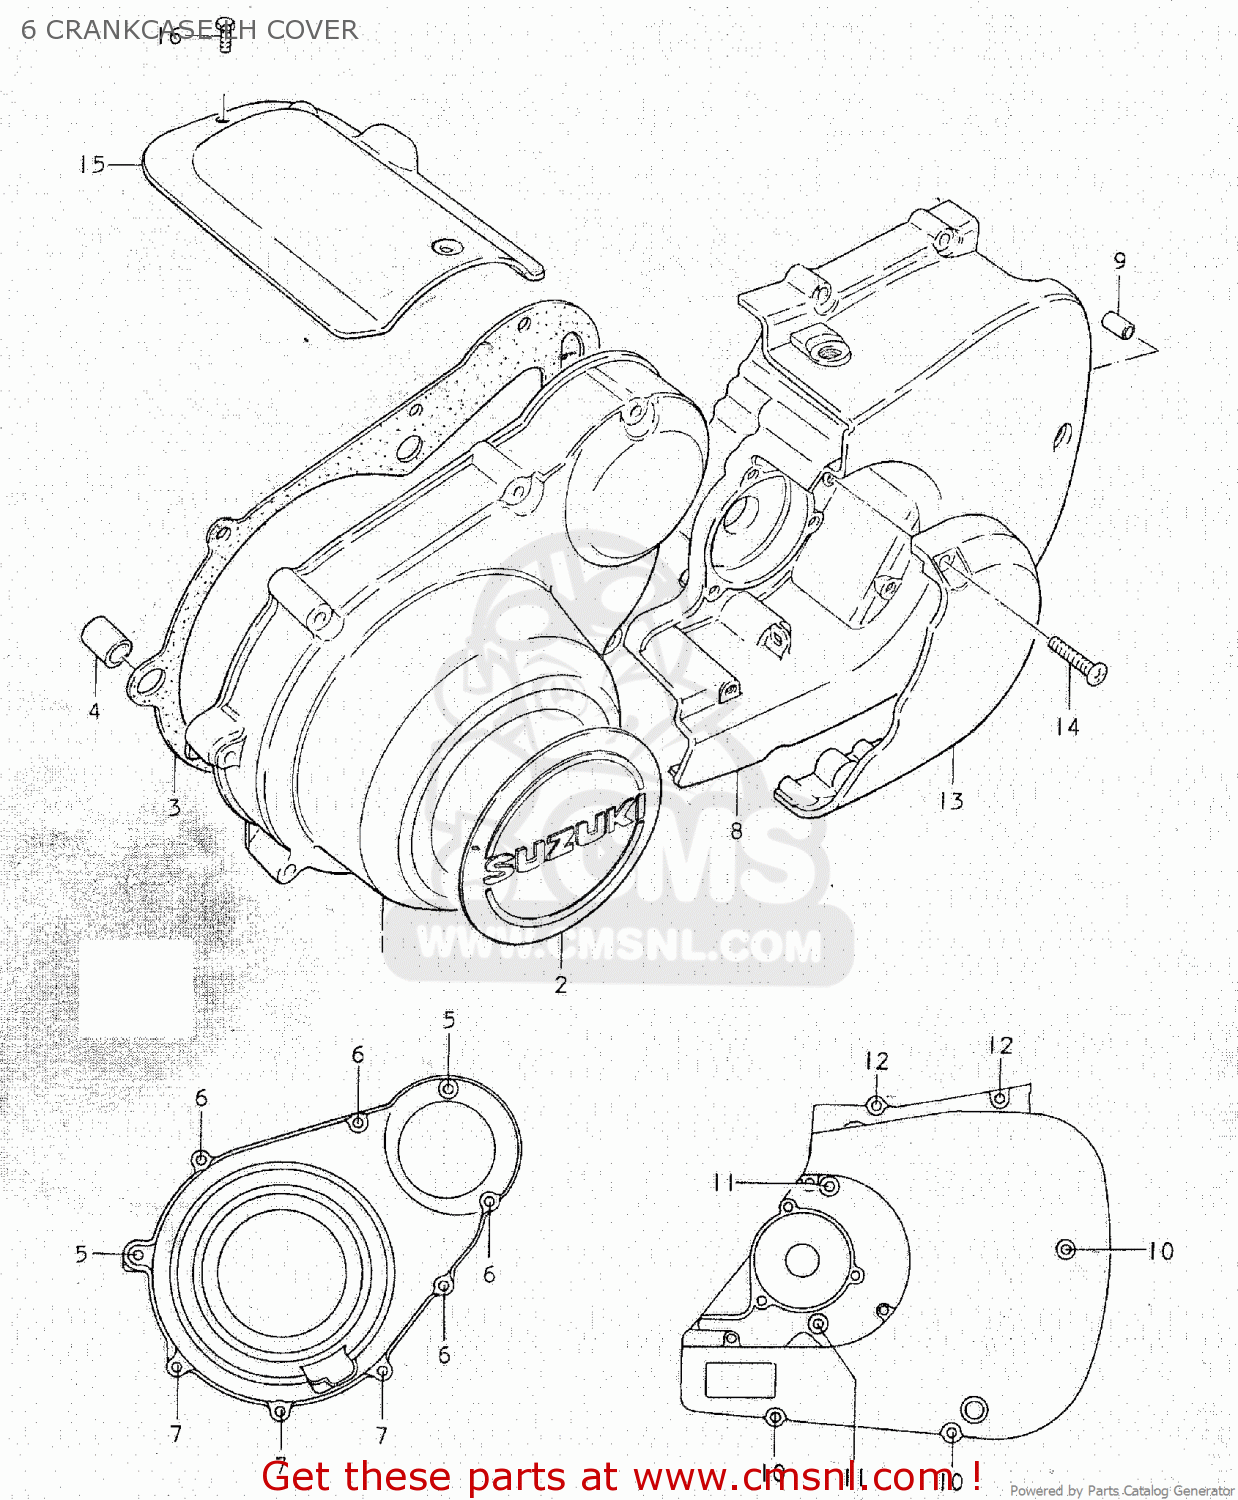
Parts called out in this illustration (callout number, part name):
1	COVER
2	EMBLEM
3	GASKET,MAGNETO COVER (MCA)
4	PIN
5	SCREW (6X45)
6	SCREW
7	SCREW (6X35)
8	COVER,ENGINE SPROCKET
9	PIN
10	SCREW 6X85
11	SCREW (6X45)
12	SCREW
13	CAP,CLUTCH RELEASE ADJUST
14	SCREW
15	COVER,STARTER MOTOR
16	BOLT 5X10
